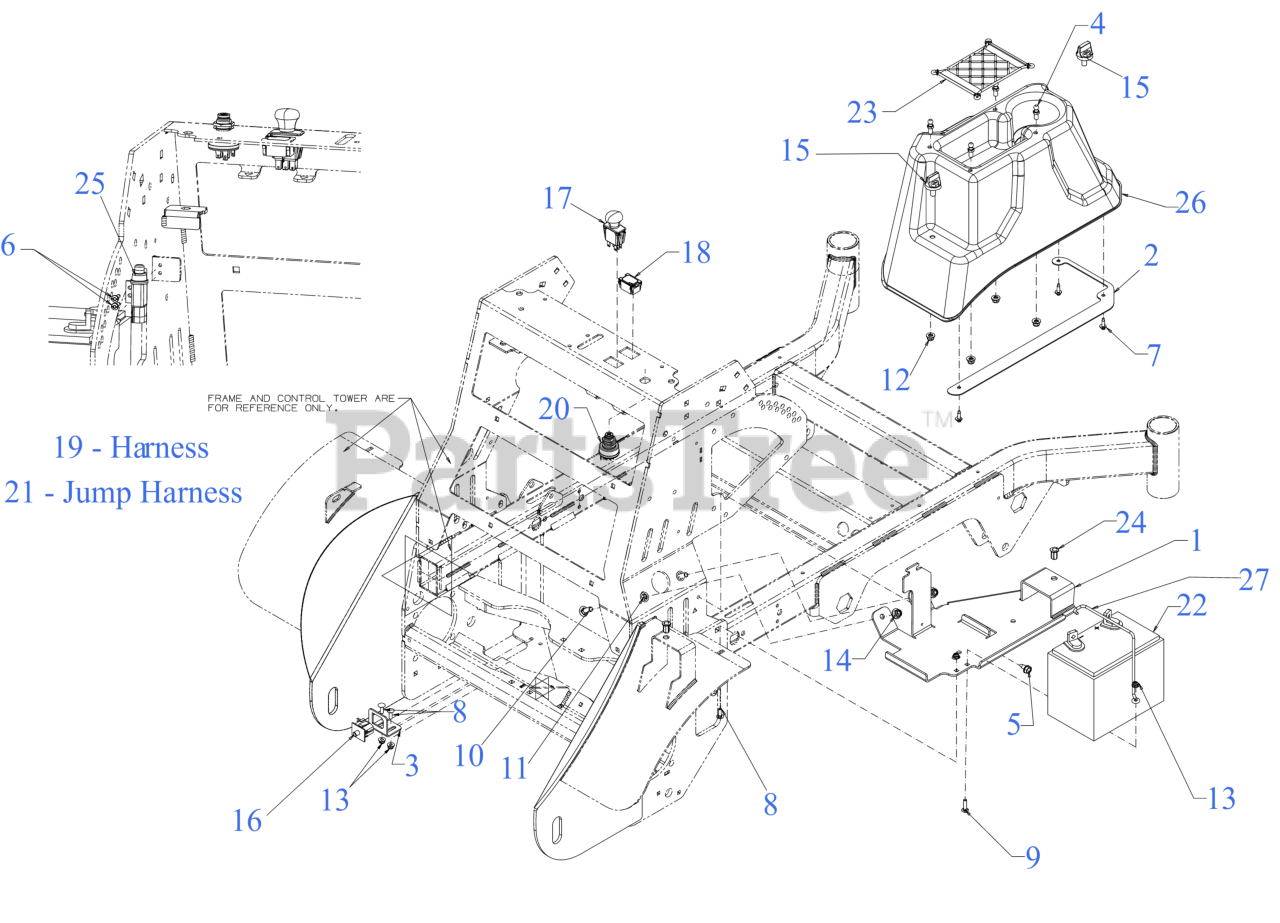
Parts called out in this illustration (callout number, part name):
1	BATTERY MOUNT BRACKET
2	BATTERY COVER SUPPORT PLATE
3	SWITCH BRACKET MOUNT
4	BALL STUD 5/16-18
5	SCREW 5/16-18 x .750
6	SCREW (10-24X.75:PH:TAP:T25:GR5)
7	SCREW 1/4-10 x .750
8	SCREW 1/4-20 x .75 GR5
9	SCREW 1/4-20 x 1 GR5
10	CARRIAGE BOLT 3/8-16 x 1.00 GR5
12	FLANGE LOCK NUT 5/16-18
13	FLANGE LOCK NUT
15	KNOB 3/8-16 x .875
16	NEUTRAL SWITCH
17	PTO SWITCH (BLACK KNOB) TEXT SYM
20	KEY SWITCH
20	PRO-Z KEY SET
21	JUMPER HARNESS (W/RELAY)
22	BATTERY (230 CCA AGM U1-280)
24	RIV NUT 3/8-16
25	SEALED PLUNGER SWITCH
26	BATTERY COVER
27	BATTERY SUPPORT ROD
